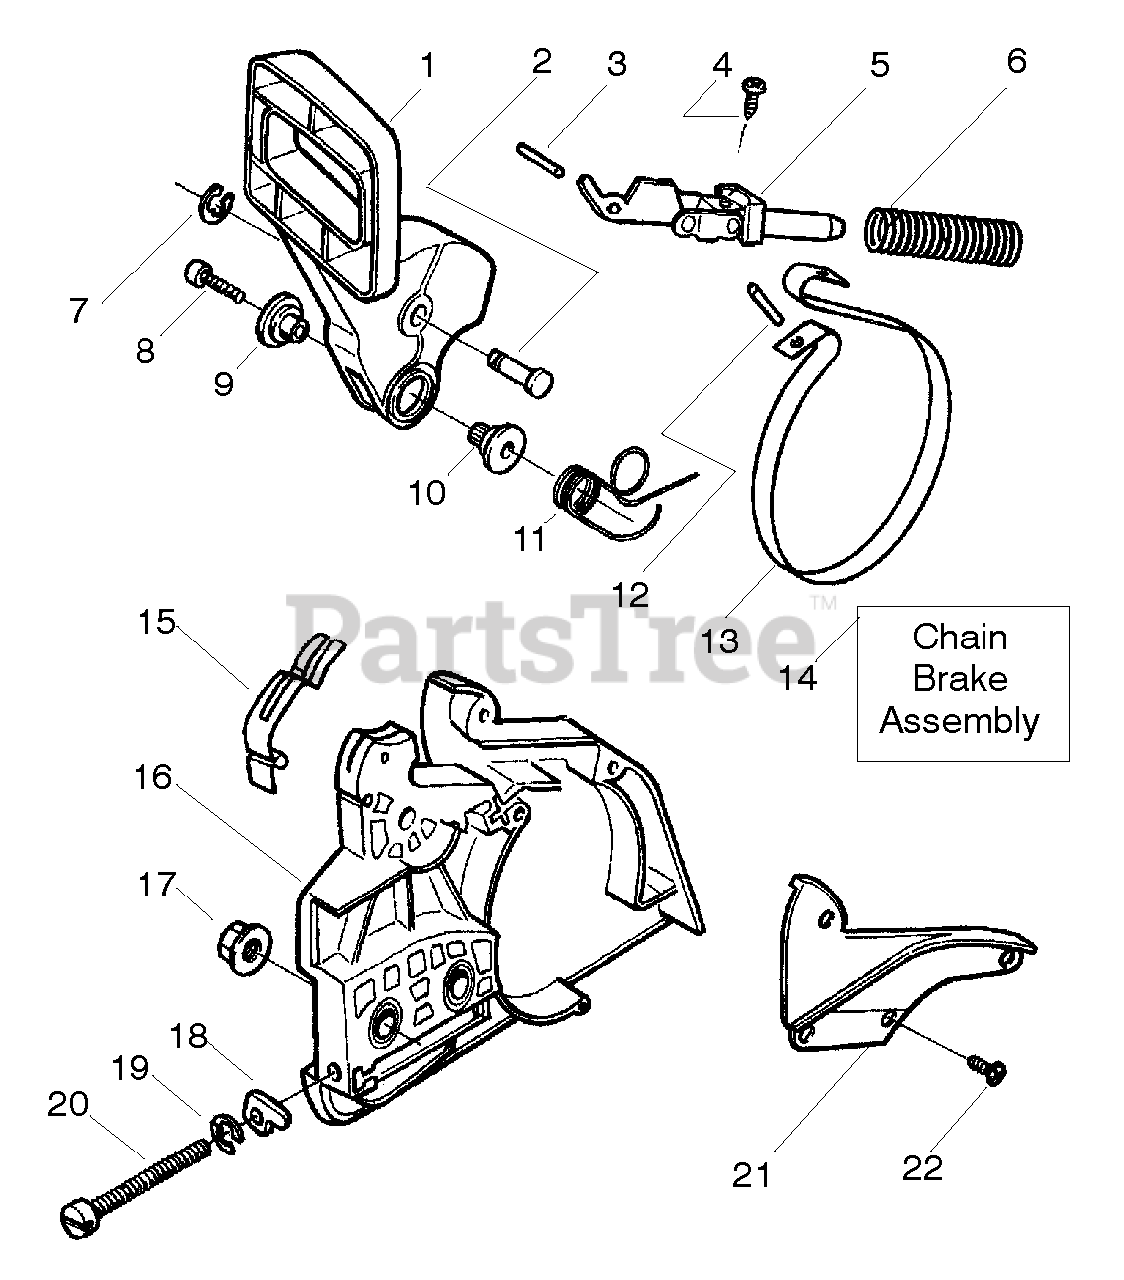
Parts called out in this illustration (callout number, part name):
1	Actuating Lever
4	Screw
5	Front Link Ass'y.
6	Chain Brake Spring
9	Journal-Right
10	Journal-Left
11	Handguard Spring
12	Pin-Spring
13	Brake Band
14	Chain Brake Assembly
15	Position Spring
16	Clutch Cover
18	Bar Adjusting Pin
20	Screw-Bar Adjusting
21	Chain Brake Spring Cover
22	Screw
